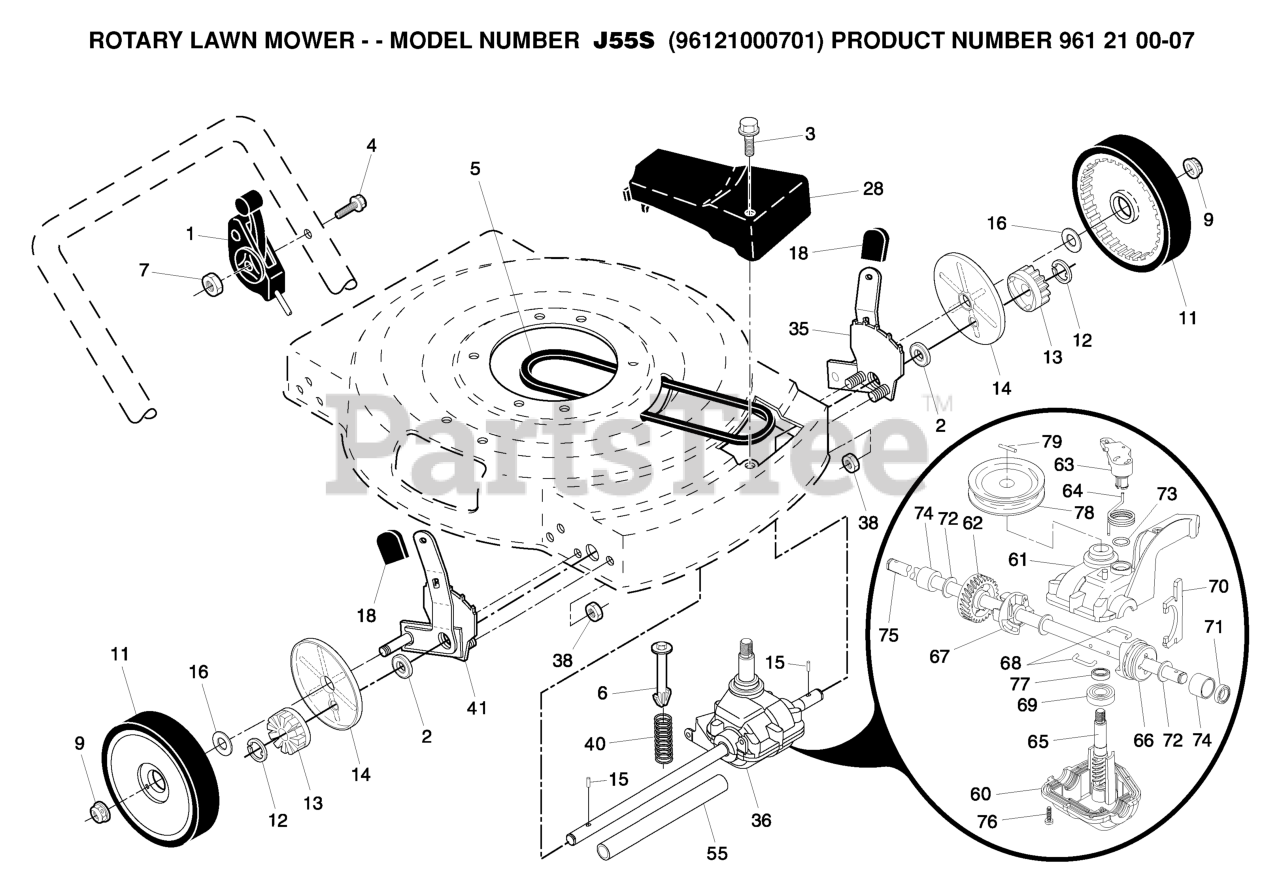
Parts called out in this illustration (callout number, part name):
1	DRIVE CONTROL 59.8 FWGD
2	RP BEARING
3	Screw, Tapping, Pan Head #10-24 x 2-3/4
4	SCREW.PAN.HEAD
5	BELT THERM .32
6	SPRING RETAINER
7	NUT.HEX.FLANGE.1/4
9	HEX FLANGE LOCKNT
11	WHEEL.8X1.75.MAG2.RAD3.GRY
12	E-RING 7/16 RE
13	PINION
14	COVER.DUST.WHEEL
15	PAWL.DRIVE
16	WASHER FLUT
18	SELECTOR KNOB
28	Drive Cover
36	TRANSMISSION.22.FGD.W/PULLEY
38	LOCKNUT.NYLOC.1/4-20
40	SPRING.EXTENSION
55	DRV SHAFT TUBE PM
60	LOWER CASE
61	UPPER CASE
62	GEAR.27.TEETH.WALK.MOWER
63	LEVER, CLUTCH
64	SPRING, RETURN
65	SHAFT INPUT (13041)
66	DOG, MOVABLE (11032)
67	DOG, FIXED GT11031
68	WIRE, FORMED (15966)
70	FORK, SHIFT
71	SEAL.OUTPUT.SHAFT
73	SEAL, CASE O-RING
75	SHAFT OUTPUT (12260 NOW 12663)
77	SEAL INPUT SHAFT
78	PULLEY.DRIVEN.FGD
79	PIN RETAINER
